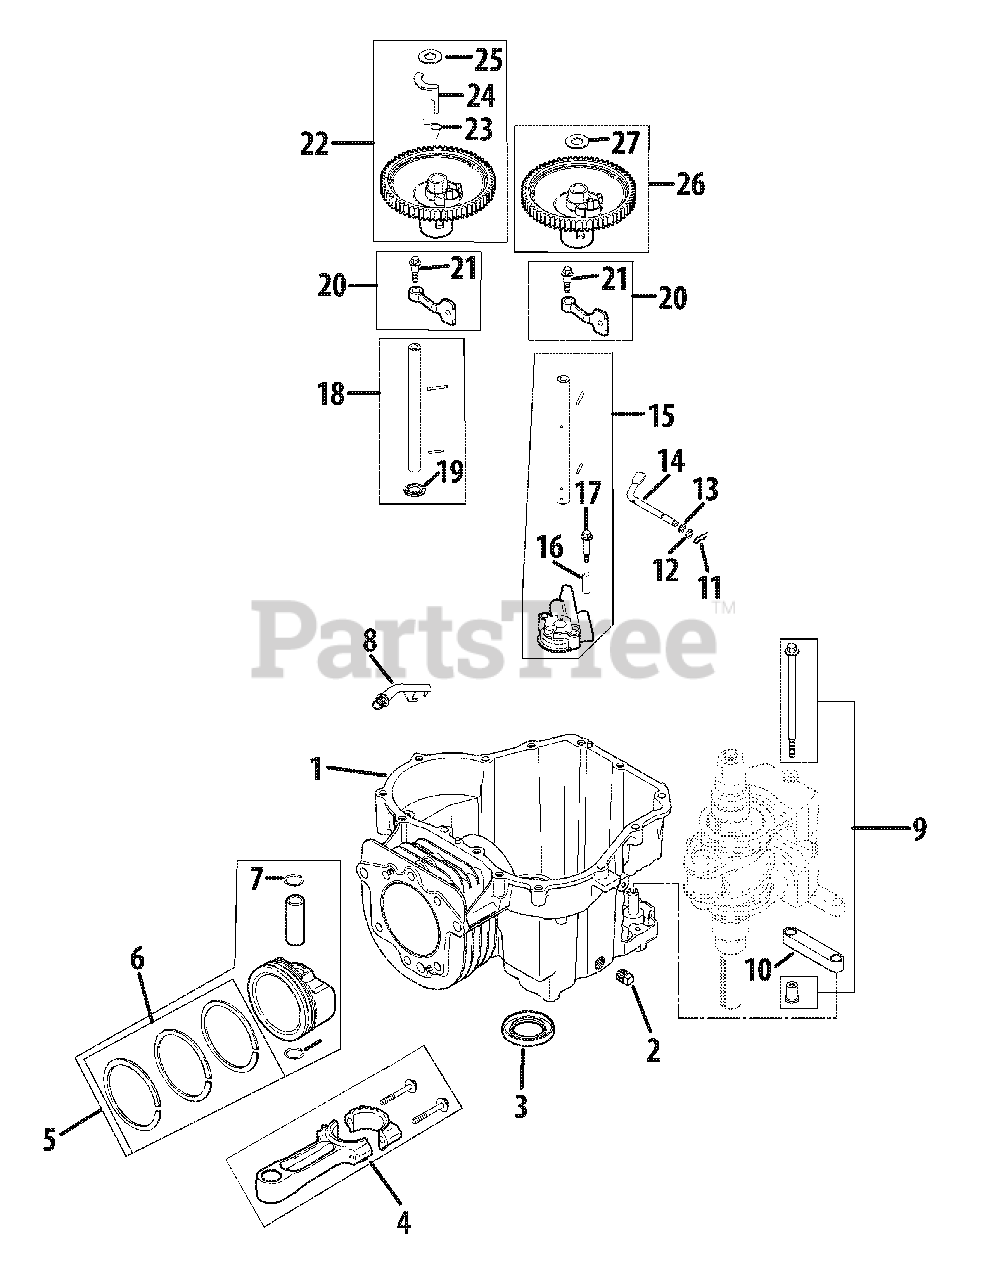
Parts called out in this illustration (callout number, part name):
1	Crankcase (USE KH-20-522-10)
2	Square Head Pipe Plug, 3/8"
3	Oil Seal
4	Connecting Rod
5	Piston w/ Ring Set Kit (Inc. 6 & 7)
6	Ring Set (94mm)
7	Piston Pin Retainer
8	Drainback Tube
9	Locating Pin Kit
10	Balance Weight Linkage
11	Hitch Pin Clip
12	Flat Washer 6mm
13	Flat Washer, 1/4"
14	Governor Cross Shaft
15	Oil Pump Assembly Kit (Inc. 16 & 17)
16	Oil Pump Screw Spacer
17	Oil pump Screw
18	Cam Center Shaft Kit
19	Thrust Washer
20	Cam Lever Assembly Kit
21	Shd Thd Frm Screw, M6 x 1 x 26
22	Camshaft Assembly Kit (Inc. 23-25)
24	ACr Weight
25	ACR Thrust Washer
26	Camshaft Assembly Kit (Inc. 27)
27	ACR Thrust Washer
